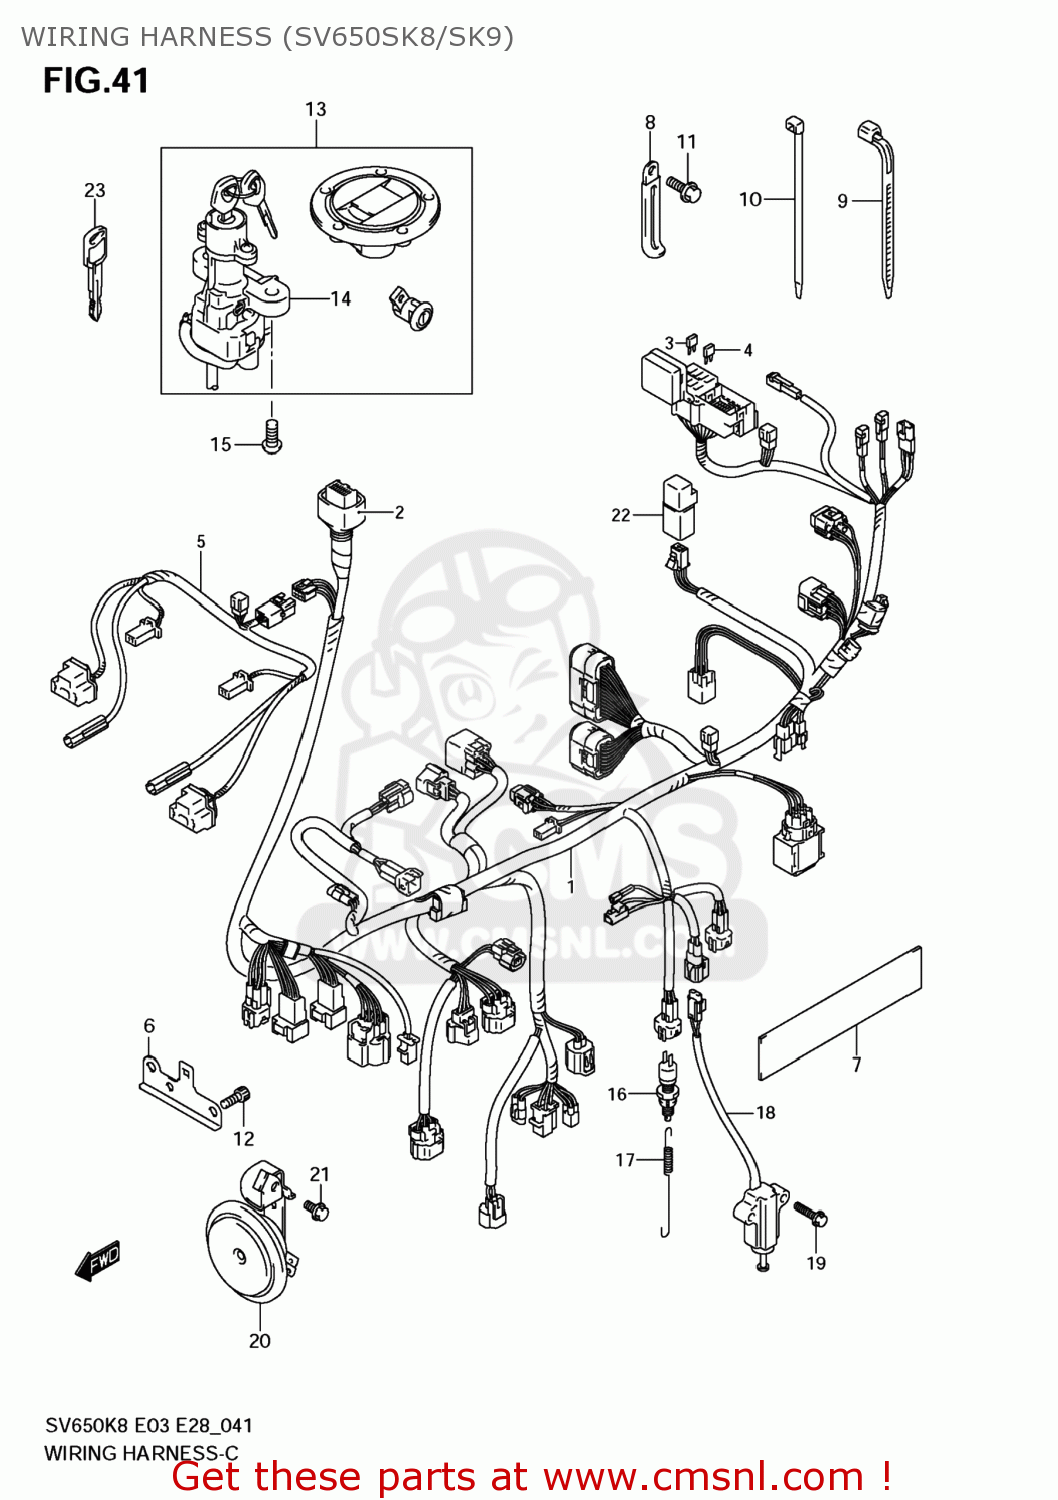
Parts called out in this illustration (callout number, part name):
1	HARNESS,WIRING NO.1
2	COVER,SPEEDOMETER COUPLER
3	FUSE(10A)
4	FUSE(15A)
5	HARNESS,WIRING NO.2
6	HOLDER,COUPLER
7	PROTECTOR(20X90)X1.0
8	CLAMP(L:45)
9	CLAMP(L:95)
10	CLAMP(L:145)
11	BOLT
12	BOLT
13	LOCK SET
14	LOCK ASSY,STEERING
15	BOLT(8X20)
16	SWITCH ASSY,STOP LAMP
17	SPRING
18	SWITCH ASSY,SIDE STAND
19	BOLT
20	HORN ASSY
21	BOLT
22	RELAY ASSY
23	KEY,BLANK
